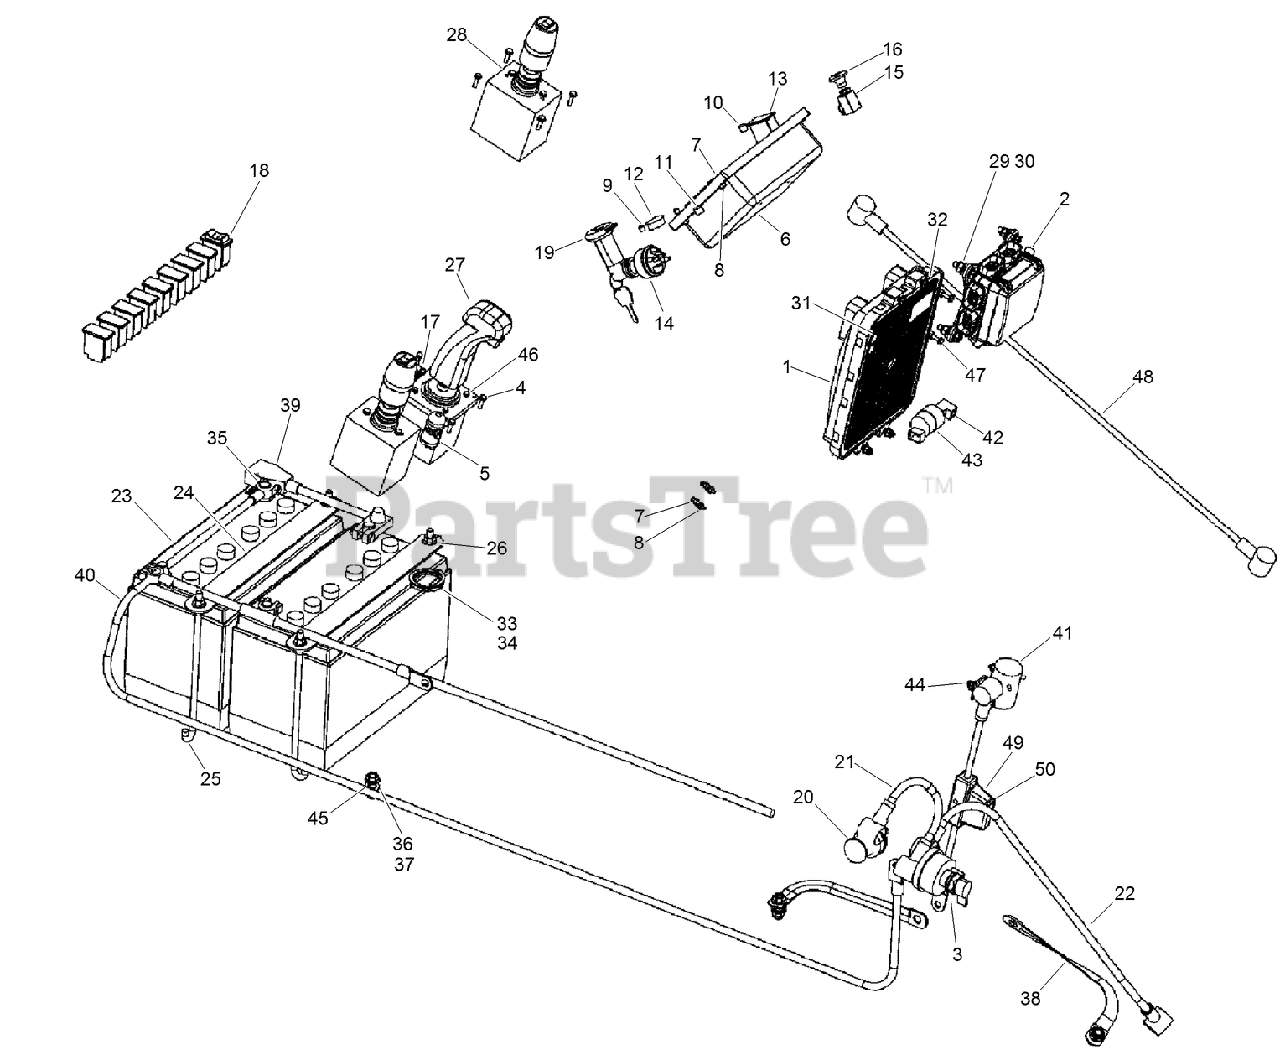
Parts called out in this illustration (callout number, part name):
1	CONTROL MODULE - with Program
2	BOX-VEHICLE, MAIN
3	SWITCH-DISCONNECT, MASTER
4	SCREW-HWH
5	SWITCH-PUSH BUTTON (SEALED)
6	DISPLAY - with Program
7	SCREW - PHd Type 1 #6 - 32 x 0.500 CST ZND
8	NUT - Prev Trq, # 6 GRA ZND NonDir
9	PLUG-DOME
10	PLUG - Dome 0.375 in Hole Black Nylon
11	PLUG - Dome 0.500 in Hole Black Nylon
12	PLUG-DOME
13	PLUG-PANEL
14	ASSEMBLY - Ignition Switch
15	SWITCH-Light
16	KNOB-Diff Lock
17	SWITCH-ROCKER, 2 POLE
18	SWITCH-ROCKER, 2 POLE (ON/OFF)
19	RECEPTICAL-12V DC
20	POST-BATTERY, REMOTE
21	CABLE-Positive
22	CABLE - Starter
23	BATTERY (purchase locally)
24	STRAP - Battery Hold Down
25	BOLT-HOLDDOWN, BATTERY
26	NUT-Serr Flg 3/8-16 UNC GR5 ZND
27	JOYSTICK-CONTROL (W/ HANDLE)
28	SINGLE AXIS JOYSTICK ASM
29	SCREW, METRIC FLANGE FULL - M8 x 25
30	NUT-TORQUE, PREVAILING
31	SCREW, METRIC FLANGE w/BODY - M6 x 35
32	NUT, METRIC FLANGE PREVAILING - M6 Zinc
33	WASHER - Lock, Receptacle Bayonet Coupling
34	NUT - Panel, Single Hole Mounting
35	CABLE-Positive
36	SCREW-HH
37	NUT-FLANGE, NYLOCK
38	STRAP-GROUNDING
39	CABLE - Dual Battery, Red (Positive)
40	CABLE - Ground
41	SOLENOID - Relay, 12V, 85A
42	FITTING-ELBOW, 90
43	SWITCH ASM
44	SCREW-HHF
45	WASHER - External Tooth Lock, 0.375 in ZND
46	SCREW - Hex Wshr Hd, TPG #8x0.875 END T
47	NUT - Prev Trq #10 GR8 ZND Insert
48	CABLE - Battery (+)
49	CABLE - Maxi Fuse Holder
